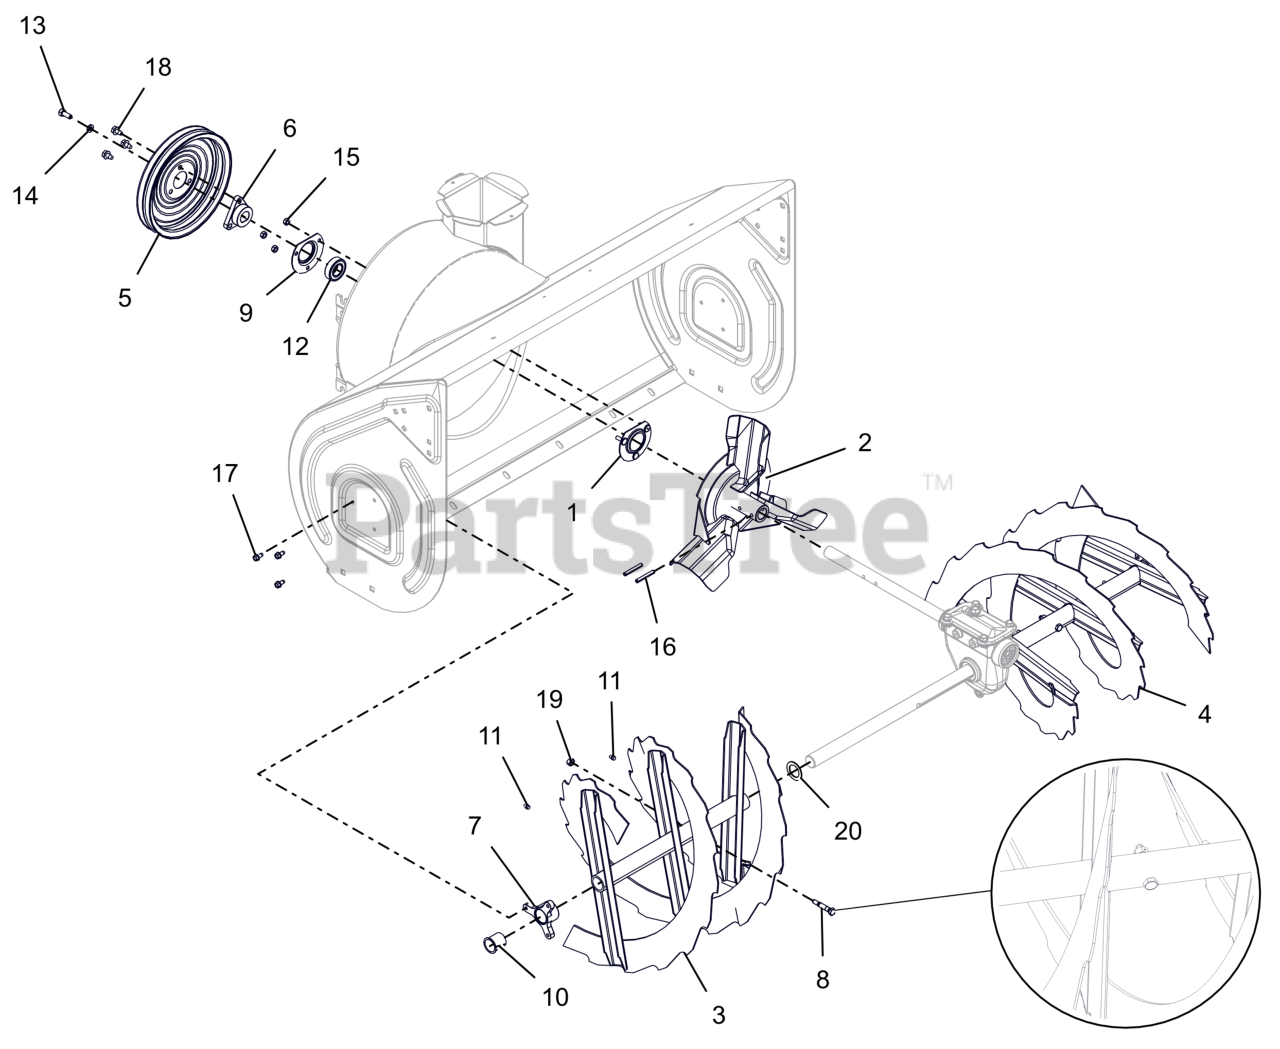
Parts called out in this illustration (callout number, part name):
1	BEARING FLANGE
2	IMPELLER, 3 BLADE-14"
3	RAKE, RH-36"(1 ID X 15.75 OD)
4	RAKE, LH-36" (1 ID X 15.75 OD)
5	PULLEY, SPIN FORM DUAL GROOVE
6	PULLEY HUB, D-BORE .87 PRO
7	BUSHING, RAKE SHAFT 1"
8	SHEAR BOLT SERVICE ASSEMBLY
9	BEARING FLANGE
10	BSHG-FLG SPLIT NYLINER 1.0" HP
11	ZERK,FITTING .25X.125 DRIVE IN
12	BRG-BALL .876X1.75X.50 RSTFP
13	BLT, HEX .31-24X.750 G5 ZCC
14	WSHR, LK-HVY .312X.097 ZCC
15	NUT,LK-CTR .25-20 GA ZCC
16	PIN-ROLL .250X1.75
17	SCR-TAP .25-20X.50 HWH ZCC
18	SCR,TAP .312-18X.50 HWH TR ZCC
19	NUT,LK-CTR .31-18 GA ZCC
20	WSHR, FLT 1.010X1.505X.062 ZCC
